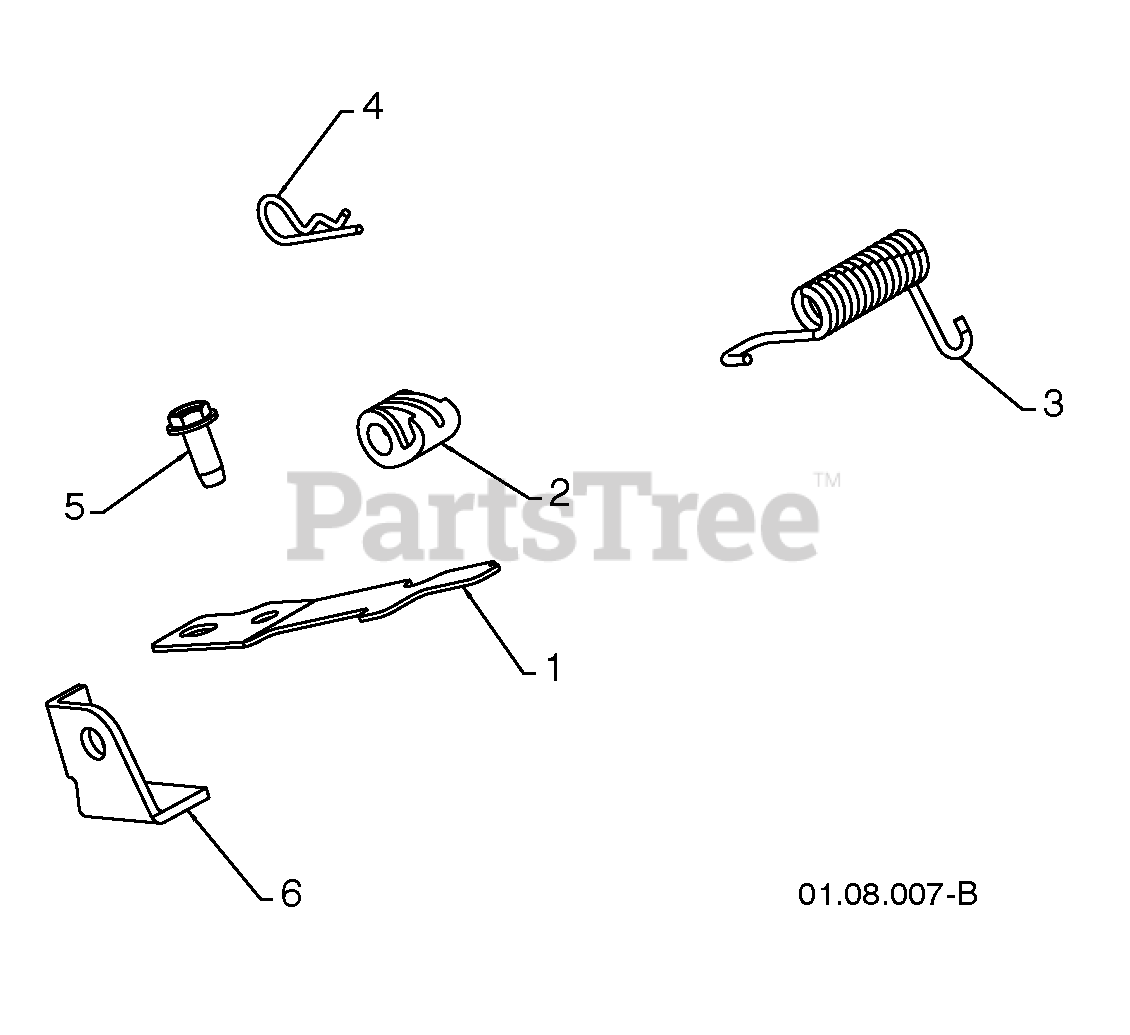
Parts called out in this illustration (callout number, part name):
1	INTERLOCK SPRING
2	INTERLOCK CAM
3	TORSION SPRING
5	SCREW 1/4-20 X .625
6	INTERLOCK STOP
